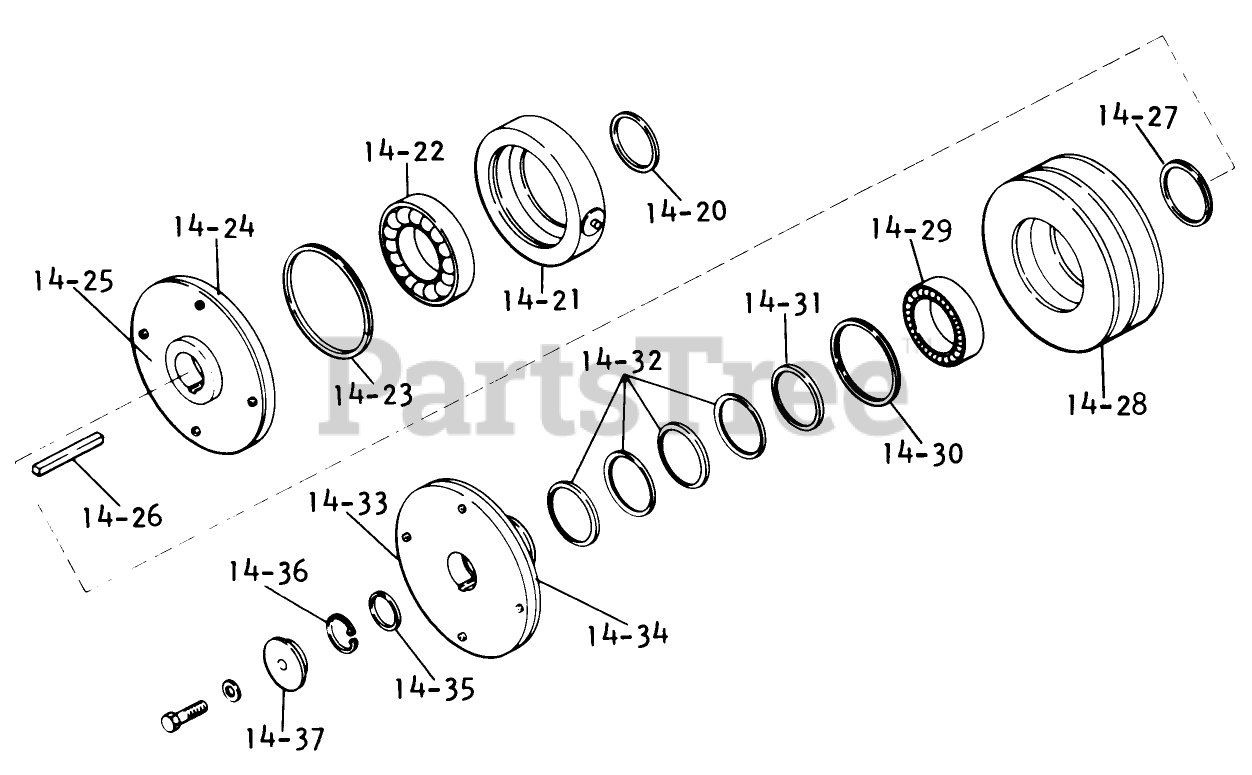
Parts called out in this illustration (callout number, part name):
14-21	ASSY COLLAR
14-22	BEARING
14-25	CLUTCH FACING
14-25	RIVET
14-27	RING EXTERNAL
14-28	PULLEY CLUTCH
14-31	WASHER
14-34	CLUTCH FACING
14-34	RIVET
14-35	WASHER
14-37	LOCKWASHER
